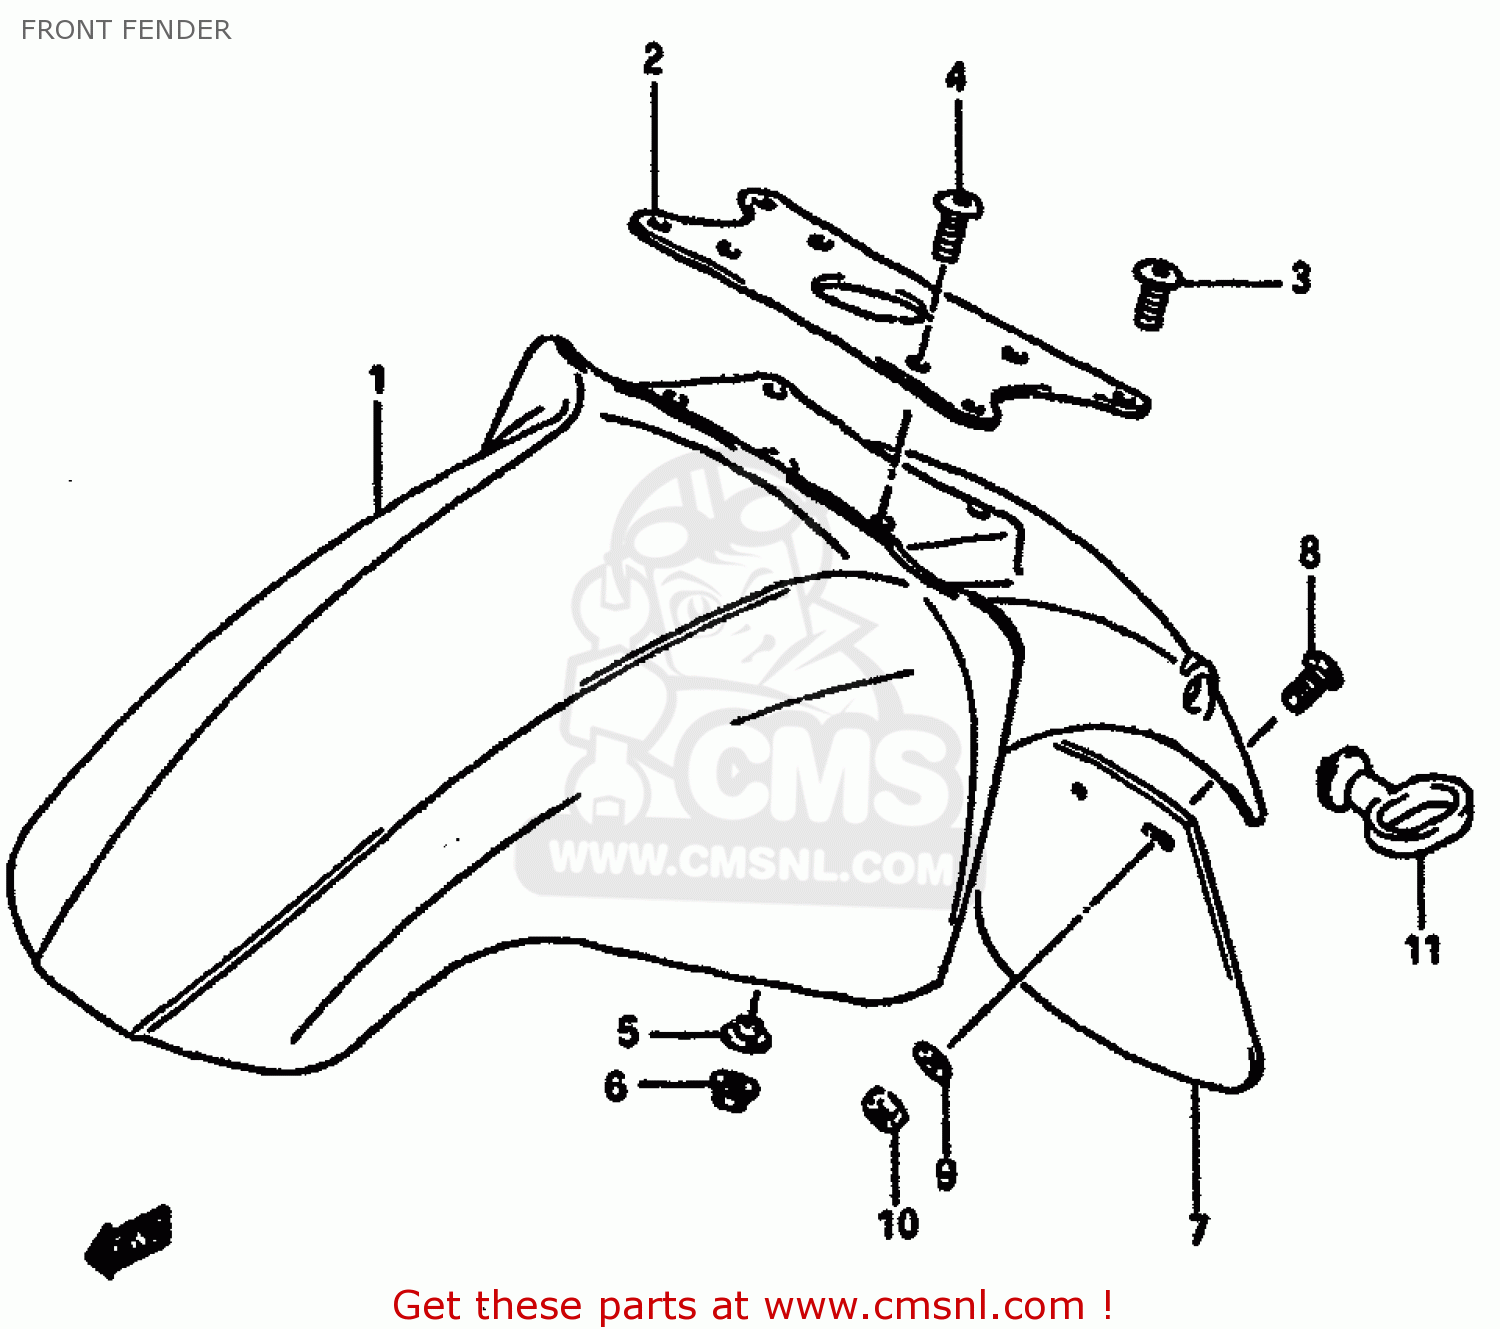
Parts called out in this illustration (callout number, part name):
1	FENDER,FRONT (WHITE)
2	BRACE,FRONT FENDER
3	SCREW(6X12)
4	SCREW(5X14)
5	WASHER
6	NUT
7	FLAP,MUD
8	SCREW
9	WASHER (5.5X16X1.2)
10	NUT
11	GUIDE,CABLE
